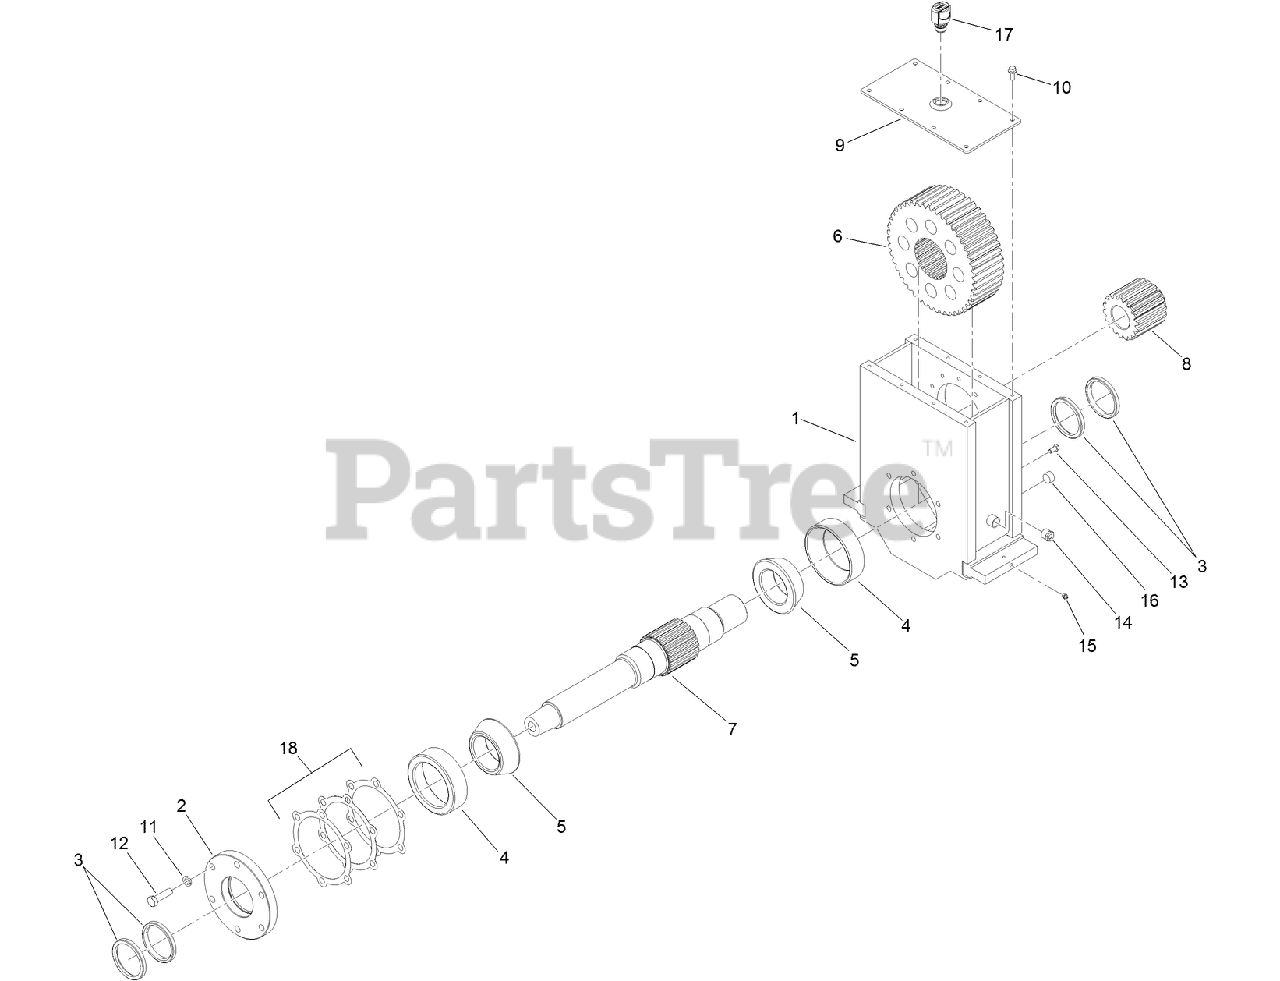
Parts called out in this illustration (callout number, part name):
1	BOX-ROTARY
2	CAP-BEARING, ROTARY
3	SEAL-SHAFT
4	CUP-BEARING
5	CONE-BEARING
6	GEAR-RING, ROTARY
7	SPINDLE-ROTARY
8	PINION-ROTARY
9	ROTARY BOX COVER
10	SCREW-HHF
11	WASHER-LOCK
12	SCREW-HH
13	SCREW-HH
14	PLUG-SITE, GLASS
15	FITTING-GREASE
16	PLUG-MAGNETIC, HEX
17	BREATHER
18	SHIM-BEARING ADJUST (.005)
